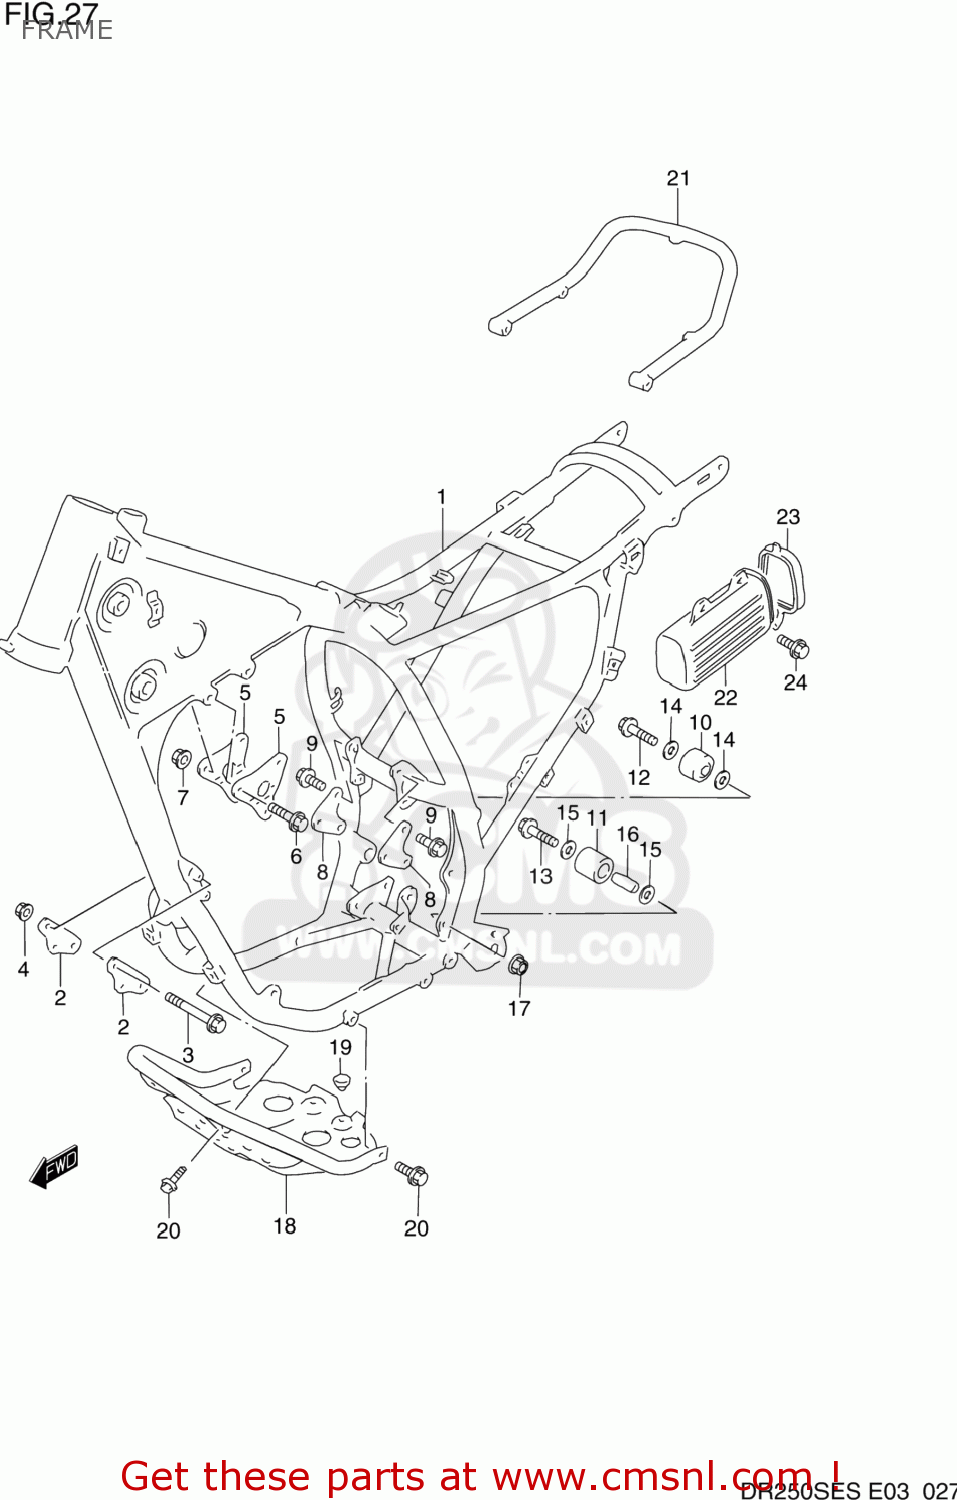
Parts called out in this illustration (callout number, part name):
1	FRAME
2	PLATE,ENGINE MOUNT FR
3	BOLT(8X85)
4	NUT
5	PLATE,ENGINE MOUNT UPR
6	BOLT(8X70)
7	NUT
8	PLATE,ENGINE MOUNTING,REAR
9	BOLT(8X16)
10	ROLLER,CHAIN
11	ROLLER,CHAIN CONTROL
12	BOLT(8X38)
13	BOLT 8X45
14	WASHER
15	WASHER
16	SPACER (8.6X13.8X28)
17	NUT
18	PROTECTOR,ENGINE
19	CUSHION
20	BOLT
21	GRIP COMP,REAR
22	HOLDER,TOOL
23	CAP,TOOL HOLDER
24	BOLT 6X16
